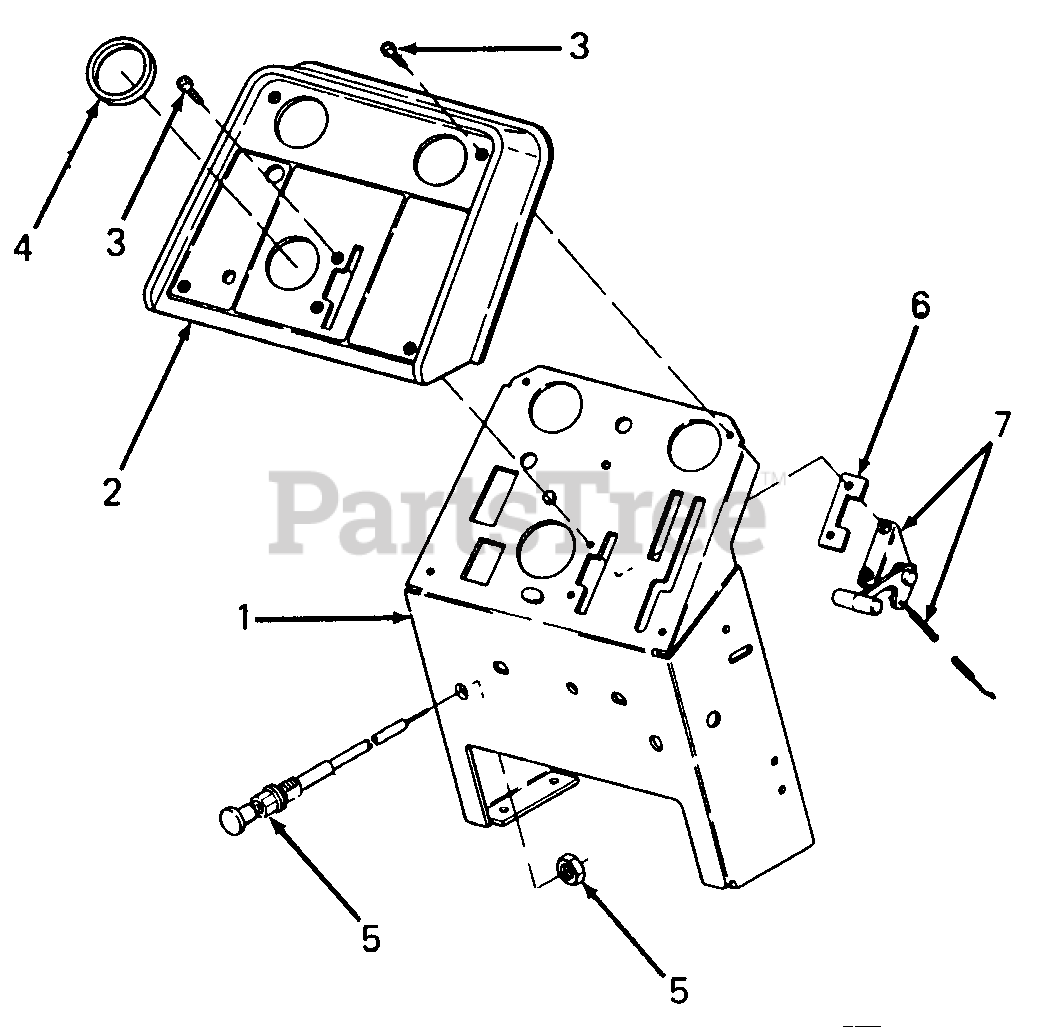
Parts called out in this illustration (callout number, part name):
2	Panel, Instrument
3	Screw, Pan Hd Cutting, #10-24 X .75 Lg
4	Grommet, Instrument Panel
5	Choke Cable w/Nut
6	Plate, Throttle Closure
7	Control, Throttle
